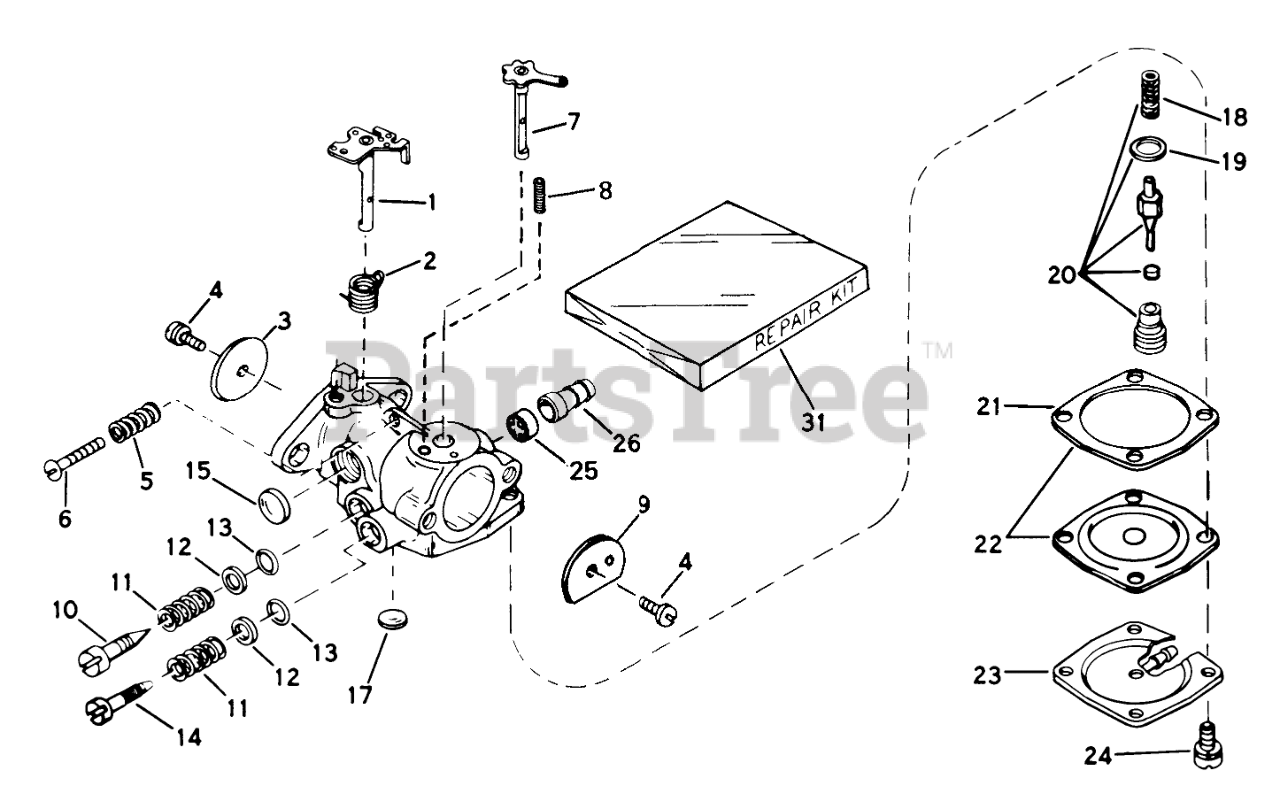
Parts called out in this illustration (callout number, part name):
1	Shaft & Lever Assy., Throttle
2	Spring Return
3	Shutter-Throttle
4	Screw-Shutter
5	Spring-Tension
6	Screw-Throttle Crack Screw / Idle Speed
7	Shaft & Lever Assembly
8	Spring-Positioning, Choke
9	Shutter-Choke
10	Screw-Idle Adjustment
13	"O"Ring
14	Screw Main Adjustment
15	Plug-Welch, Idle Mixture Well
17	Plug Welch
18	Spring-Valve
19	Gasket-Valve Seat
20	Inlet Needle, Seat, Spring & Gasket Assembly (Incl. Nos. 18 & 19)
21	Gasket-Diaphragm
22	Diaphragm Assembly (Incl. No. 21)
23	Cover, Diaphragm
24	Screw, Diaphragm Cover
25	Valve Check
26	Fuel Fitting
31	Kit-Repair
